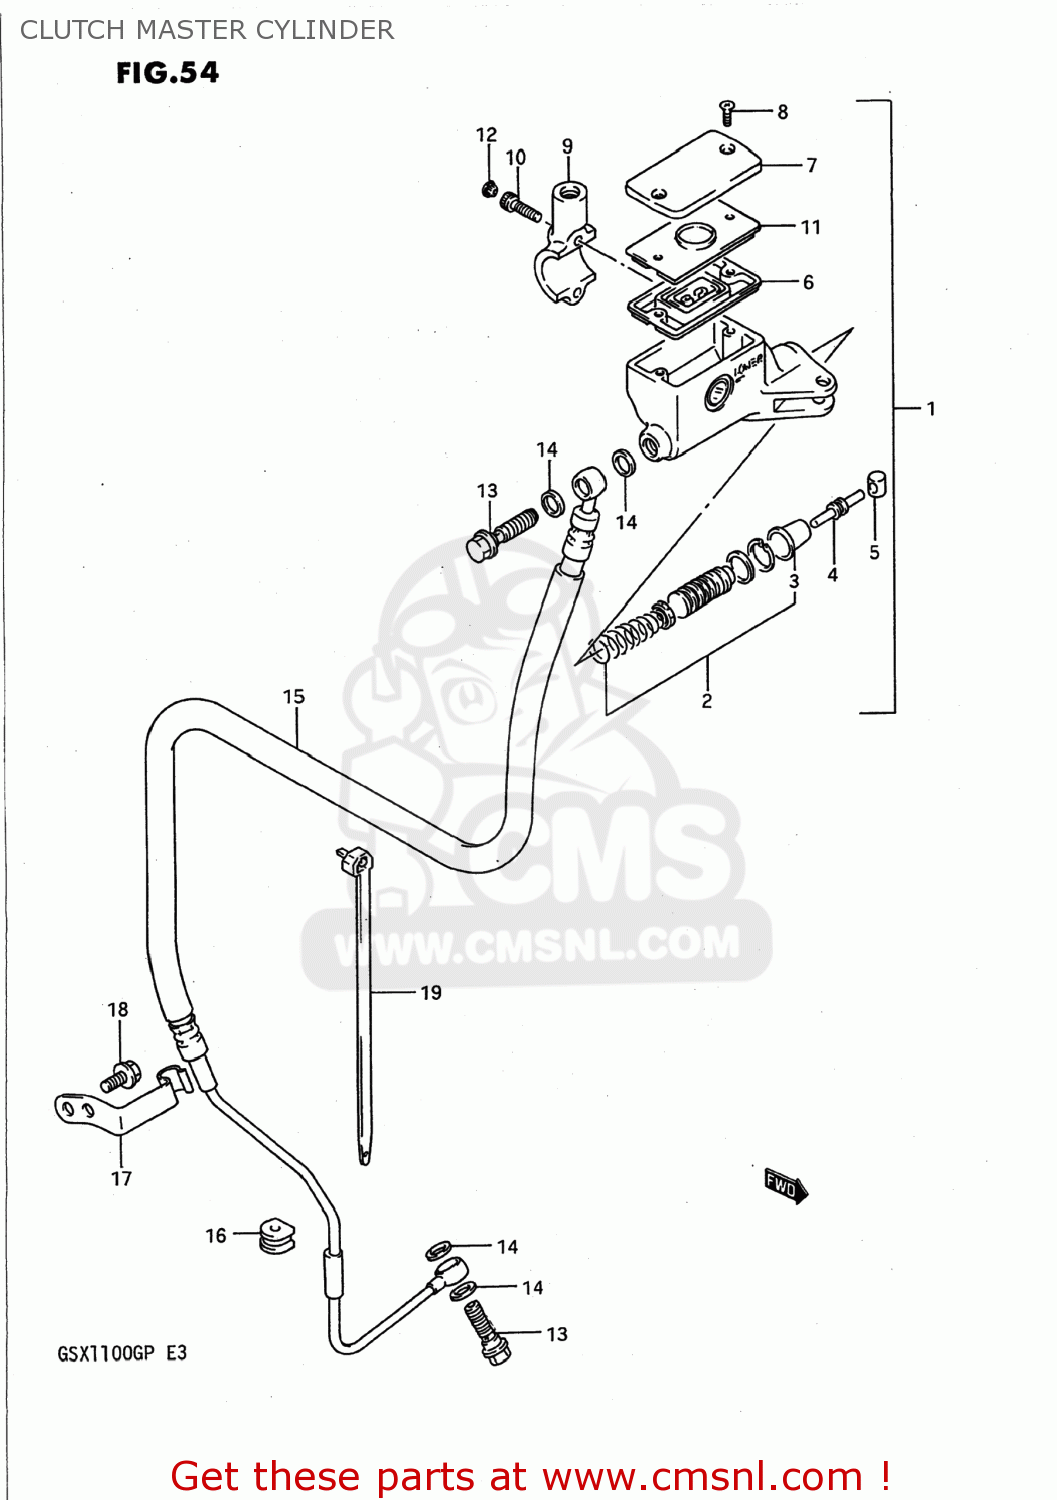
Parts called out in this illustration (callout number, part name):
1	CYLINDER ASSEMBLY,CLUTCH MASTER
2	PISTON & CUP SET
3	BOOT
4	PUSH ROD
5	BUSH
6	7
7	CAP
8	SCREW,RESERVOIR CAP
9	HOLDER
10	BOLT ,6X20
11	PLATE,DIAPHRAGM
12	CAP(OD:10)
13	BOLT UNION
14	WASHER(10X15X1.5)
15	HOSE,CLUTCH
16	GROMMET,CLUTCH HOSE
17	GUIDE,CLUTCH HOSE
18	BOLT
19	CLAMP
